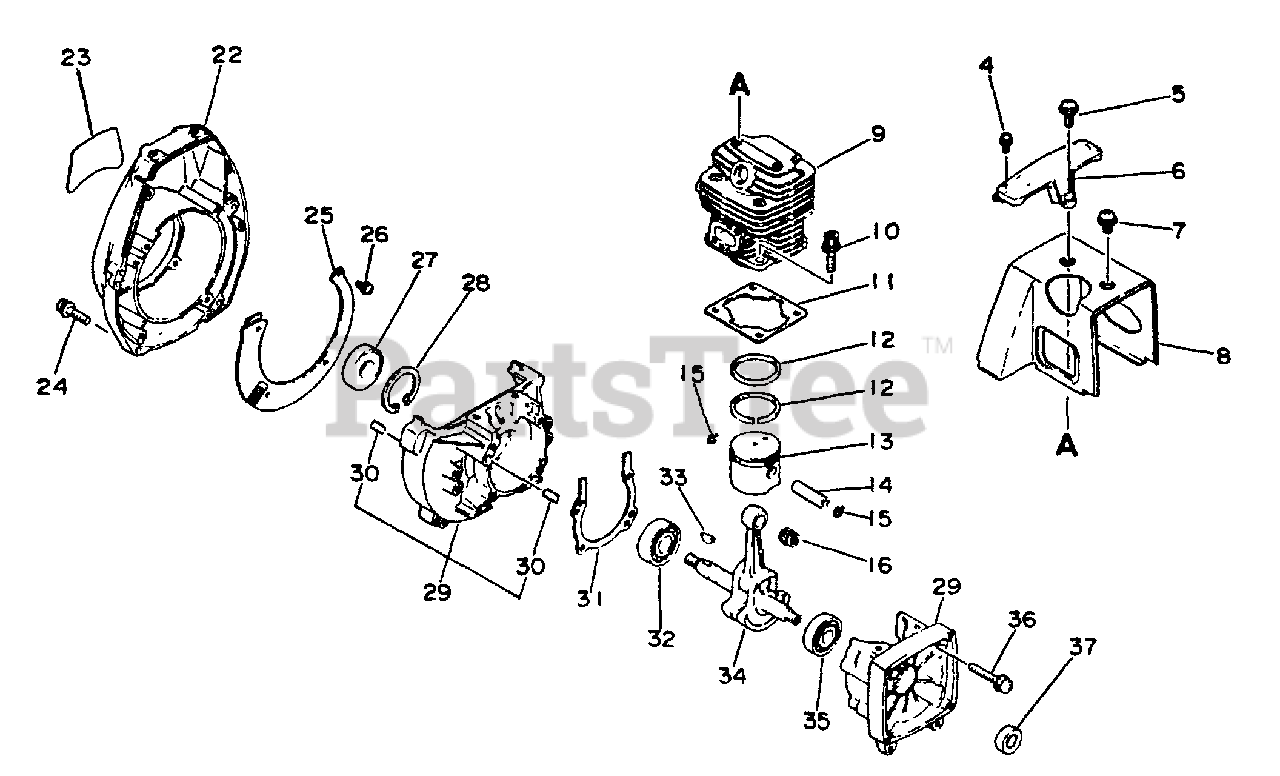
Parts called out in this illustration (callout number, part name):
4	SCREW 4×14
5	SCREW 5×16
6	GUARD, TOP
7	SCREW 5×10
8	COVER, CYLINDER
9	CYLINDER
10	BOLT 5×20
11	GASKET, CYLINDER
12	RING, PISTON
13	PISTON
14	PIN, PISTON
15	RING, RETAINING
16	BEARING, NEEDLE 9
22	COVER, FAN
24	SCREW 5×25
25	PLATE, GUIDE
26	SCREW 4×8
27	SEAL, OIL
28	RING, SNAP 35
29	CRANKCASE KIT
30	PIN, LOCATING 5×10
31	GASKET, CRANKCASE
32	BEARING, BALL 6202
34	CRANKSHAFT
35	BEARING, BALL - 6201 C3
36	SCREW 5×30
37	SEAL, OIL 12
